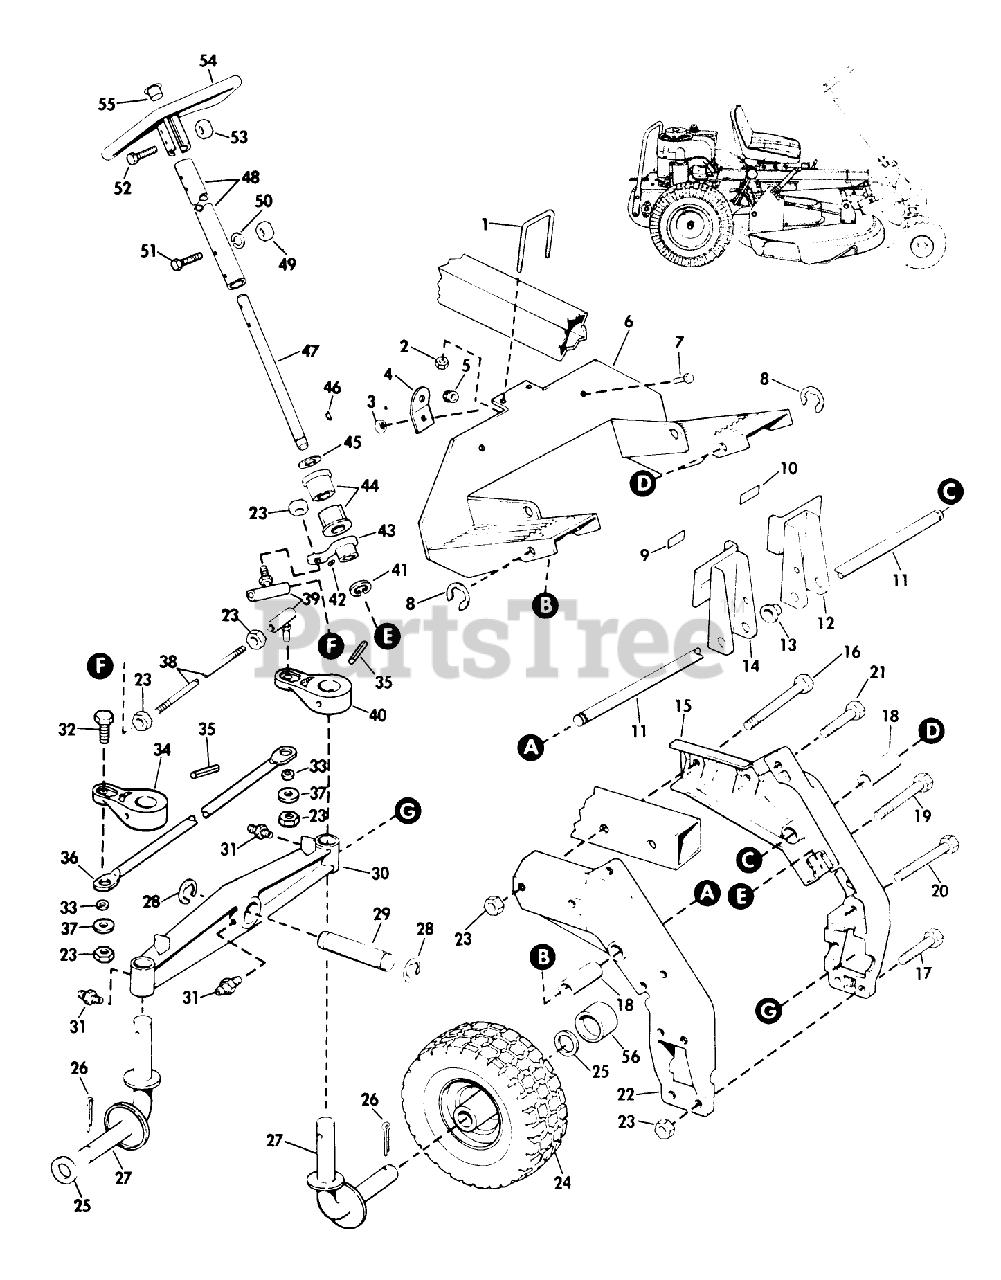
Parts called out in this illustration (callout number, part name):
5	Bushing
26	Cotter Pin-Front Wheel
31	Grease Fitting
32	Screw-King Pin
53	Nut-Steering Shaft
